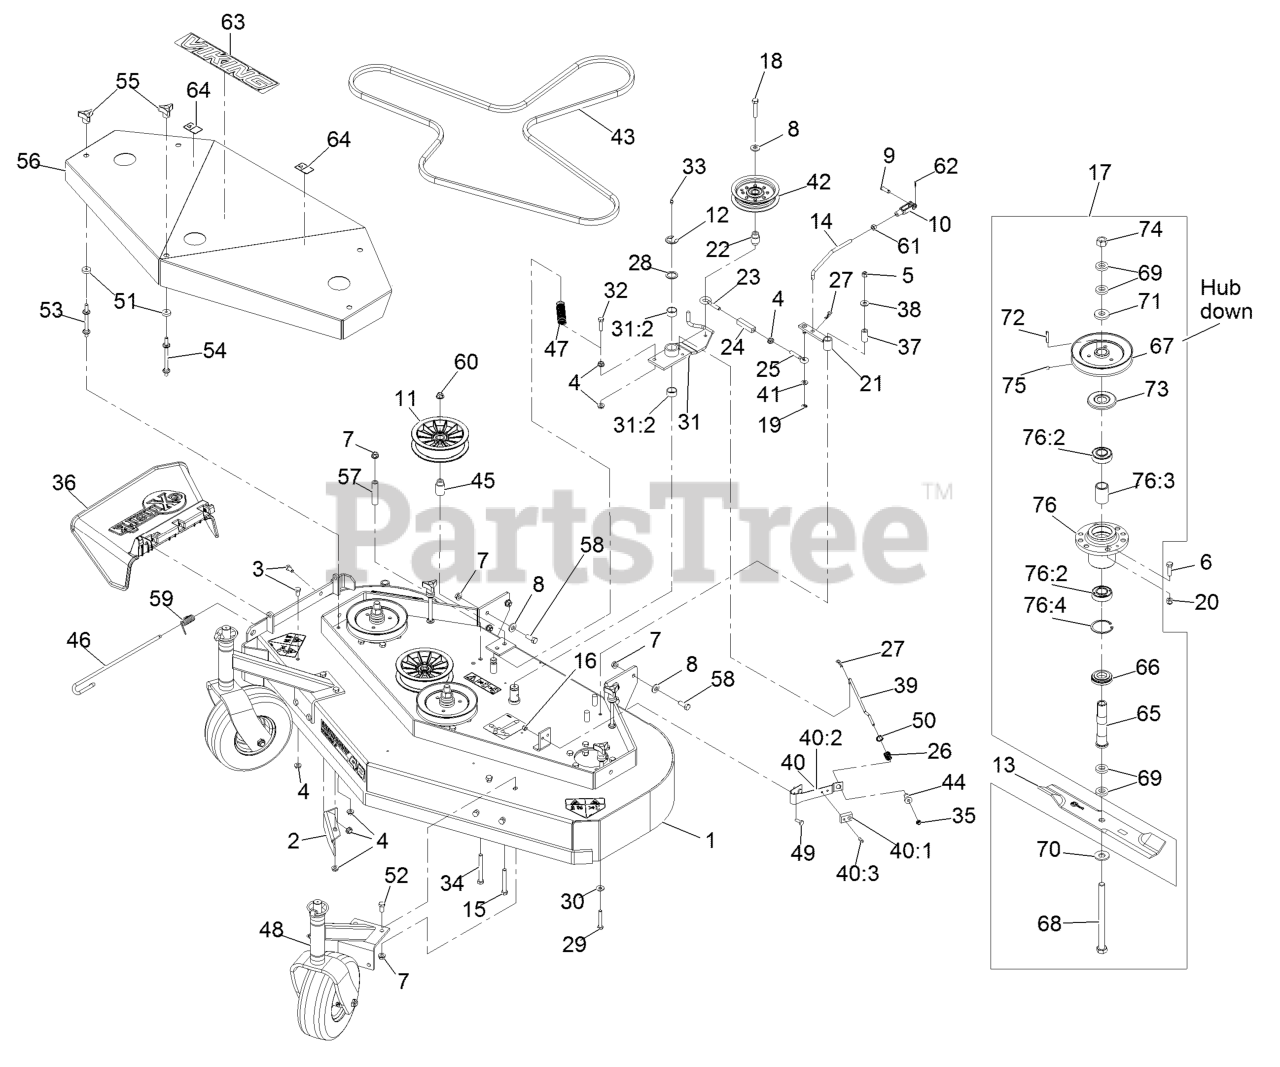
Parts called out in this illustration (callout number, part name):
1	DECK-SERVICE, 48
2	BAFFLE-DOGLEG
3	SCREW-HH
5	NUT-LOCK, NI
6	SCREW-HH
7	NUT-HHF, WHIZ
8	WASHER-BELLEVILLE
9	PIN-CLEVIS
10	YOKE-ADJUSTABLE
11	PULLEY,IDLER 5"
12	RING-RETAINING, EXT
14	ARM-LINKAGE, ASSIST
15	SCREW-HH
16	NUT-LOCK, NI
17	ASM, CUTTER HOUSING OUTER
18	SCREW-HH
19	RING-RETAINING, EXT
20	NUT-LOCK, NI
21	ARM-ASSIST, 32/36
22	BUSHING-ENGAGEMENT
23	EYEBOLT-THREAD, LH
24	BODY-TURNBUCKLE
25	EYEBOLT-THREAD, RH
26	SPRING-COMPRESSION
27	PIN-COTTER
28	WASHER-SPINDLE
29	SCREW-HH
30	WASHER-SPRING
31	IDLER ARM ASM
31:2	SLEEVE-BEARING
32	SCREW-HH, SPECIAL
33	FITTING-GREASE
34	SCREW-HH
35	NUT-LOCK, NI
36	CHUTE DEFLECTOR XRK M056
37	TUBE-PIVOT
38	WASHER-FLAT
39	ROD-BRAKE
40	PAD AND SPRING ASM
40:1	PAD-BRAKE
40:3	RIVET-POP
41	WASHER-PLAIN
43	BELT,BLADE 48
44	SPACER-FLANGED
45	BUSHING-IDLER
46	PIN-CHUTE
47	SPRING-EXTENSION
48	ASM-CASTER MNT W/WEIGHT
49	SCREW-HH
50	RING-PUSH ON
52	SCREW-HH
53	STUD-SHIELD, BELT (SHORT)
54	STUD-SHIELD, BELT (LONG)
55	KNOB-3 PRONG
56	ASM,SHIELD W/DECALS 48 VI
56	Shield-Belt
58	SCREW-HH
59	SPRING, TORSION
60	NUT-HF, NI
61	NUT-HEX
62	PIN-COTTER
63	DECAL, VIKING HYDRO MODEL
64	DECAL-WARNING
65	TUBE-SPINDLE, SHORT
66	SPACER-GUARD, BOTTOM
67	SHEAVE
68	SCREW-CAP, HH
70	WASHER-SPRING
71	WASHER-RETAINER, SHEAVE
73	GUARD-BEARING, TOP
74	NUT-HEX
75	SETSCREW
76	Cutter Housing ASM
76	KIT, CUTTER HOUSING
76:2	BEARING-JACKSHAFT
76:3	SPACER-BEARING
76:4	RING-SNAP
